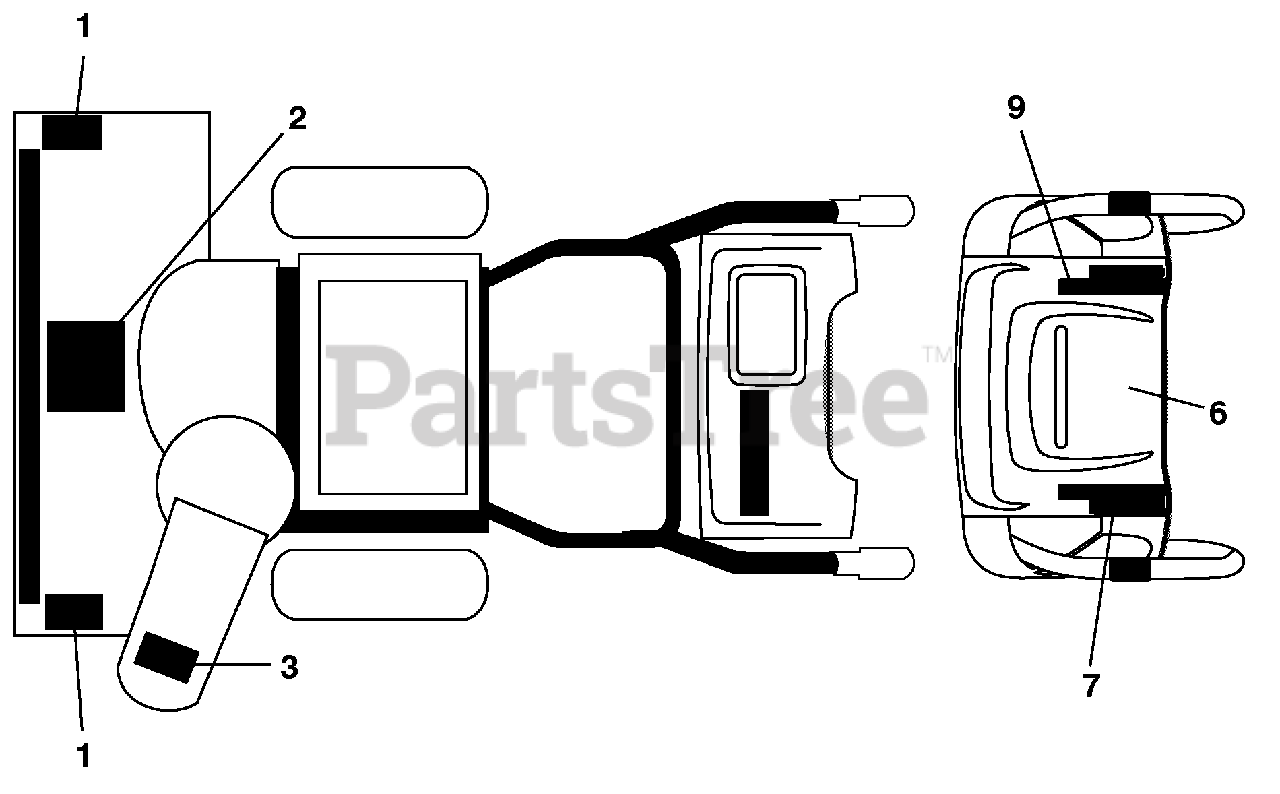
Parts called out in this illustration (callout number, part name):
1	DECAL, DANGER
2	DECAL, DANGER
3	DECAL, DANGER, DEFLECTOR
6	DECAL, INSTRUCTION
7	DECAL, CONSOLE, LT SPD/LEV/PWRST
9	DECAL, CONSOLE, RT SPD/LEV/PWRST
9	OWNER'S MANUAL, ENGLISH
9	OWNER'S MANUAL, FRENCH
